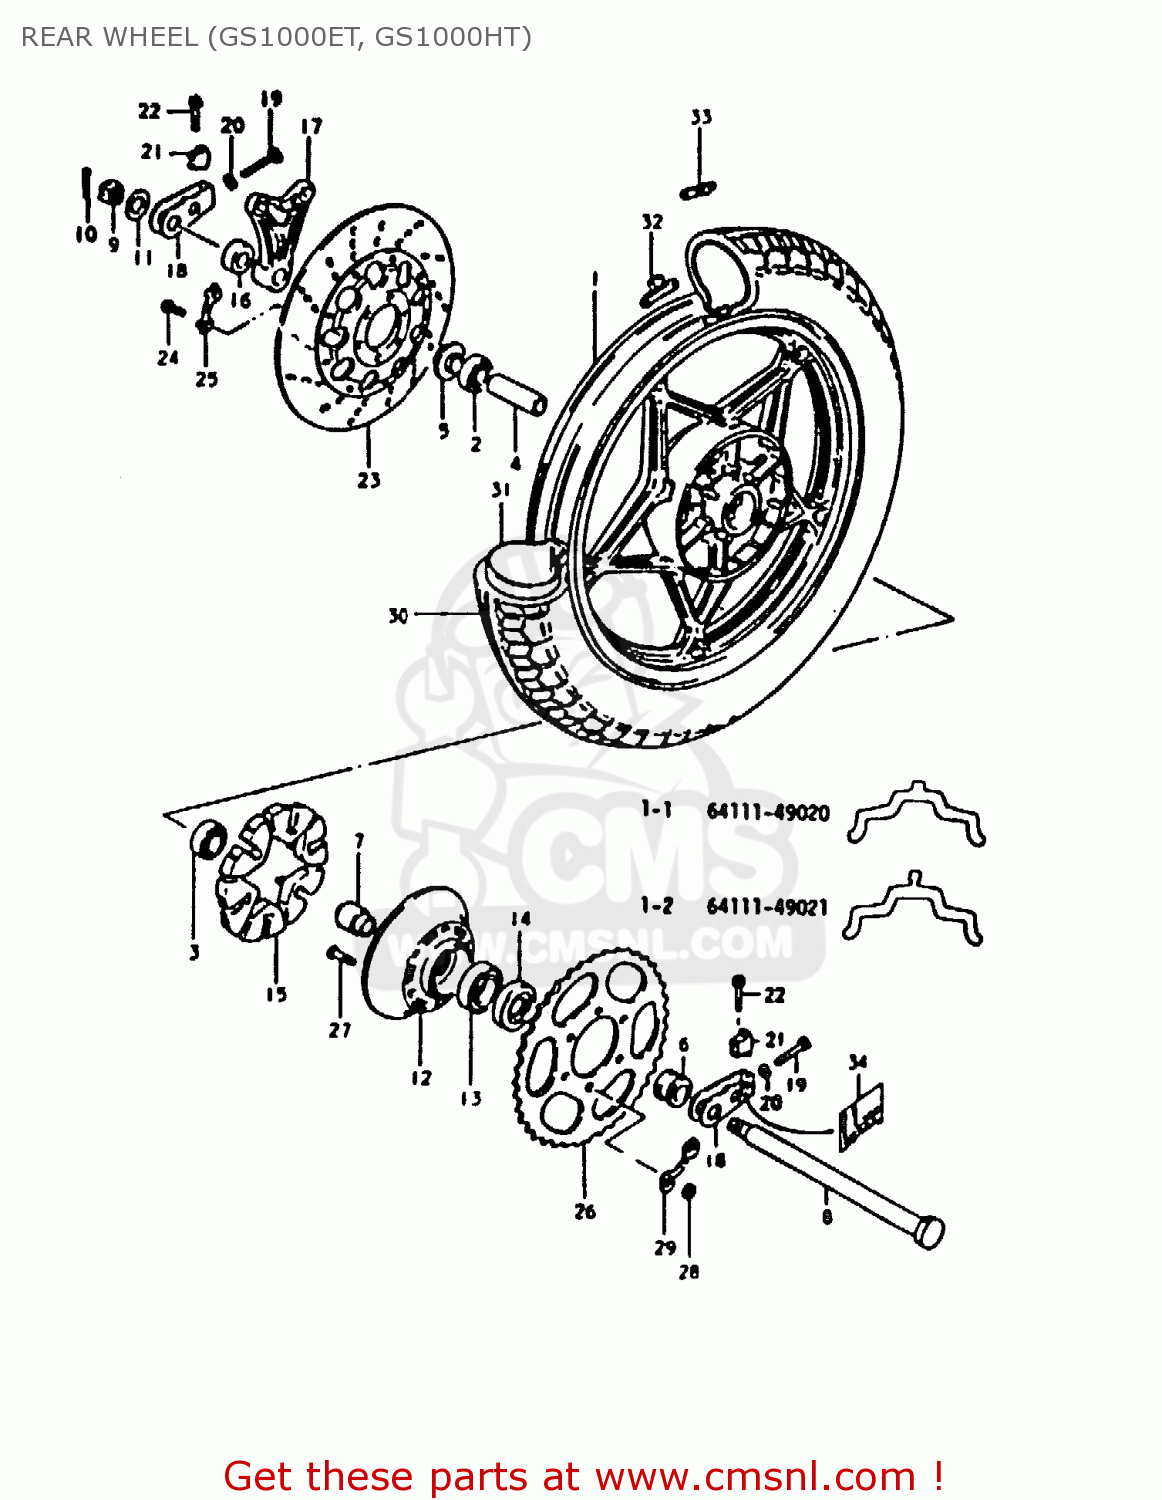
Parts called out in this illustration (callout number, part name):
1	WHEEL,REAR
2	BEARING WHEEL REAR(20X47X14)
3	BEARING, LH
4	SPACER(20.5X28X88)
5	SPACER,REAR AXLE
6	SPACER(20X33X28.3)
7	SPACER,REAR HUB BEARING
8	AXLE,REAR
9	NUT 18MM
10	PIN,COTTER
11	WASHER(19X34X4)
12	DRUM,REAR SPROCKET MOUNT
13	BEARING
14	SEAL,OIL(33X62X7)
15	ABSORBER,REAR HUB SHOCK
16	SPACER(20X38X12)
17	BRACKET,RR,CALIPER
18	ADJUSTER,CHAIN
19	BOLT
20	NUT
21	SUPPORTER,CHAIN ADJUST
22	BOLT (8X40)
23	DISC,RR BRAKE
24	BOLT(8X30)
25	WASHER
26	SPROCKET,REAR
27	BOLT
28	NUT
29	WASHER
30	TIRE
31	TUBE ASSEMBLY,WHEEL,INNER
32	BALANCER,WHEEL
33	BALANCER,WHEEL
34	LABEL,CHAIN WEAR INDICATOR
